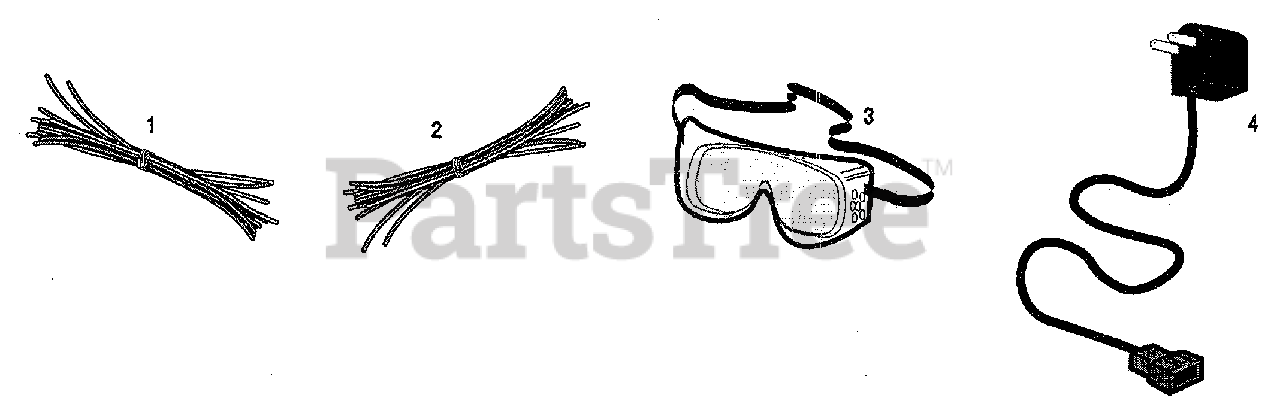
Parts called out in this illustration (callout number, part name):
1	Trimmer String Kit, .155"
2	Trimmer String Kit, .130"
3	Safety Goggles
4	Battery Charger (Electric Start Model)
